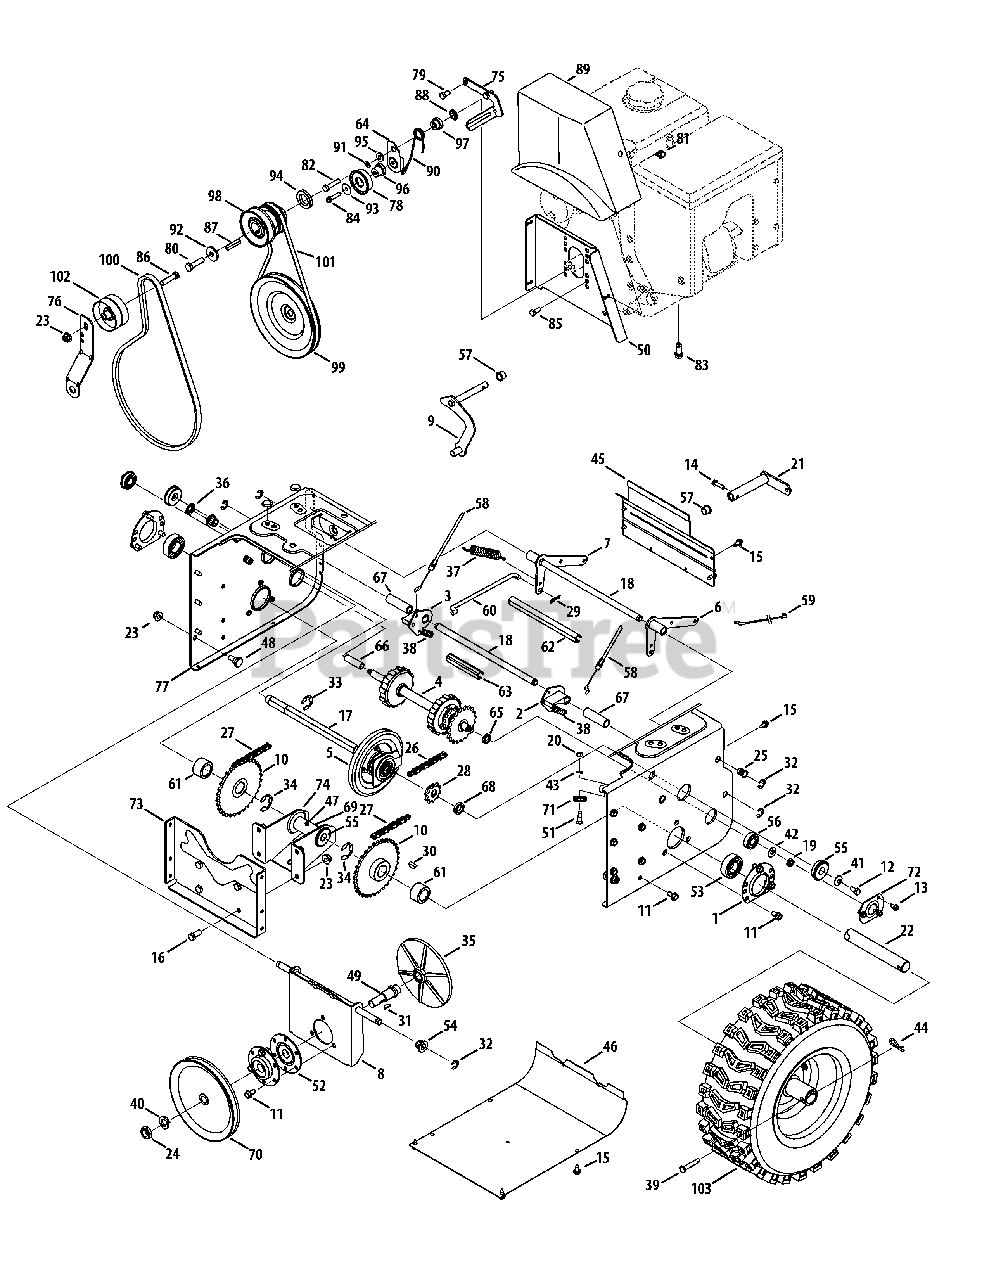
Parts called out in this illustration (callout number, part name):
1	Housing, Bearing
2	Dogg, Steering Drive, LH
3	Dogg, Steering Drive, RH
4	Shaft Assembly, Steering
5	Assembly, Friction Wheel
5	Wheel, Friction, Bonded
5	Screw, Hex Wash
6	Bracket, Auger Actuator
7	Bracket, Drive Actuator
8	Brkt, Friction Drive Suprt.
9	Rod Assembly, Shift
10	Sprocket, 32T
11	TT Screw, 5/16-18 x .750
12	Screw, Hex Cap Lock,
13	Screw, Self-tapping, 1/4-20, 0.500
14	Shift Arm Assembly
15	Screw, Hex Wash.
16	Screw, Hex Cap, 3/8-16
17	Shaft, Hex Drive
18	Shaft, Actuator
19	Nut, Hex Insert Jam Lock
20	Nut, Hex, 1/4-28 GR5
21	Screw, Self-tapping, 1/4-20, 1.00
22	Axle, Wheel, 33" & 30"
22	Axle, Wheel, 28"
23	Flange Lock Nut, 3/8-16
24	Hex Nut, 5/8-18
25	Nut, Insert 3/8-16
26	Chain, Endless, #41 x 36L
27	Chain, #420 x 40L
28	Sprocket, #41 x 10T
29	Pin, Internal Cotter
30	Key, Woodruff
31	Key, Hi-Pro, 3/16 x 5/8
32	E-Ring
33	Ring, Retaining
34	Ring, Retainer
35	Plate, Drive
36	Speed Nut, .500
37	Spring, Extension
38	Spring, Extension
39	Pin, Clevis
40	Washer, Lock, 5/8
41	Wsh, Bell., .34 x .872 x .06
42	Wash, .375 x .812 x .060
43	Washer, Lock, 1/4
44	Pin, Internal Cotter
47	Fitting, Lube, 3/16 Drive
48	Screw, Shldr., .498 x .34
49	Spindle, Drive Plate
50	Belt Cover Bracket
51	Screw, Hex Shldr., 1/4-28
52	Ass’y, Bearing/Housing
53	Bearing, Self Aligning
54	Bearing, Hex Flange
55	Bearing, Ball
56	Bush, Flg, .5625 x 1.375 x .4375
57	Bush, Flg, .5 ID x .627 OD
58	Steering Cable, 34.78" Long
59	Cable, Auger Idler
60	Rod, Drive Clutch
61	Spacer, 1.0 ID x 1.50 OD
62	Spacer, .51 ID x 7.895 Lg.
63	Spacer, .51 ID x 3.66 Lg.
64	Idler Drive Wheel Bracket
65	Spacer, .566 ID x .87 OD x .190
66	Spacer, .566 ID x .87 OD x 1.25
67	Spacer, .514 x .632 x 2.44
68	Spacer, .675 x 1.0 x .23
69	Spacer, .6725 x 1.125 x 2.48
70	Pulley, Auger
71	Roller, Cable
72	Bearing Retaining Bracket
73	Bracket, Frame Support
74	Bracket, Axle Support
75	Belt Keeper Bracket
76	Bracket, Auger Idler
78	Idler Pulley Assembly
79	Screw, Hex Cap, 5/16-24
80	Hex Hd. Screw, 3/8-24 x 1.25 GR8
81	Screw, Hx Wash Hd Tapp
82	Screw, Hex Cap, 5/16-24 x 1.50
83	Screw, 3/8-16 x 1.00
84	Screw, 1/4-20 x 1.25
85	Screw, Shldr., .500 x .145
86	Hex Head Screw, 3/8-16 x 1.75
87	Square Key, 1/4 x 1.50
88	Nut, Push
89	Cover, Belt
90	Torsion Spring, .850 dia. x .333 lg.
91	Washer, Lock, 5/16
92	Washer, Flat, .406 x 1.25
93	Washer, Flat, .265 x 1.0 x .030
94	Spacer, 1.155 ID x 1.50 OD x .15
95	Shoulder Spcr., .3175 x .500 x.094
96	Shoulder Spacer, .260 x .785 x .538
97	Shoulder Spacer, .340 x 1.00
98	Double Pulley, 3.25 x 2.75
99	Pulley, Drive
100	V-Belt, 4L x 44.60 Lg.
101	V Belt, 3/8 x 36.68
102	Pulley, Flat Idler, 2.75 OD
103	Wheel Ass’y. - LH, 33" & 30"
103	Wheel Ass’y. - RH, 33" & 30"
103	Wheel Ass’y. - LH, 28"
103	Wheel Ass’y. - RH, 28"
